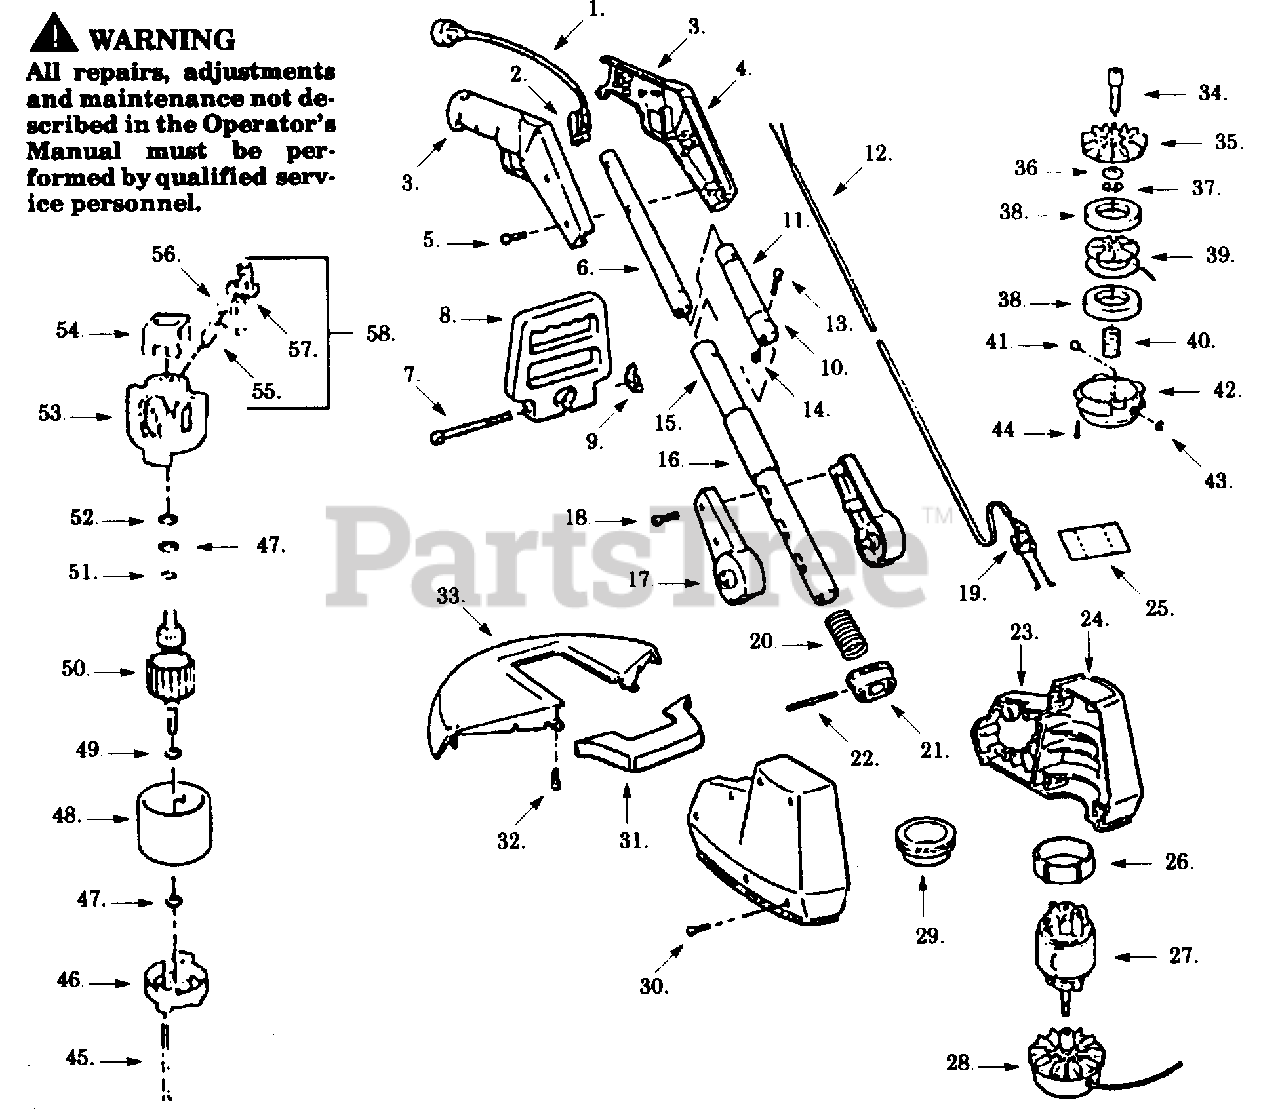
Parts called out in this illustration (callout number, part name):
1	Power Cord
2	Trigger Switch
3	Handle Set
4	Handle Label (Not a serviceable part)
6	Upper Tube
8	Assist Handle Ass'y.
9	Wing Nut
10	Outer Tube
11	Warning Label (Not a serviceable part)
12	Harness Ass'y.
14	Stop Nut
15	Lower Tube
16	Sponge Grip
17	Pivot Set
19	P.C. Bridge Ass'y.
22	Sleeve Pin
23	Housing Set
24	Hsg. Top Label
25	Shield Insulator
26	Adapter Ring
27	Motor Ass'y.
28	Cutting Head Ass'y.
29	Air Baffle
31	Front Guard
33	Guard & Blade Ass'y.
34	Drive Adapter
35	Rear Plate
37	Retaining Ring
38	Foam Pad
39	Spool & Line
42	Hub Ass'y.
43	Wire Retaining Ring
44	Cotter Pin
46	Endbell Ass'y. (Drive)
48	Field Ass'y.
49	Retaining Ring
50	Armature Ass'y.
51	Retaining Ring
53	Endbell Ass'y. (Brush)
54	Insulator
55	Carbon Brush
56	Brush Spring
57	Brush Holder
58	Brush Kit (Incl. 55,56,57)
